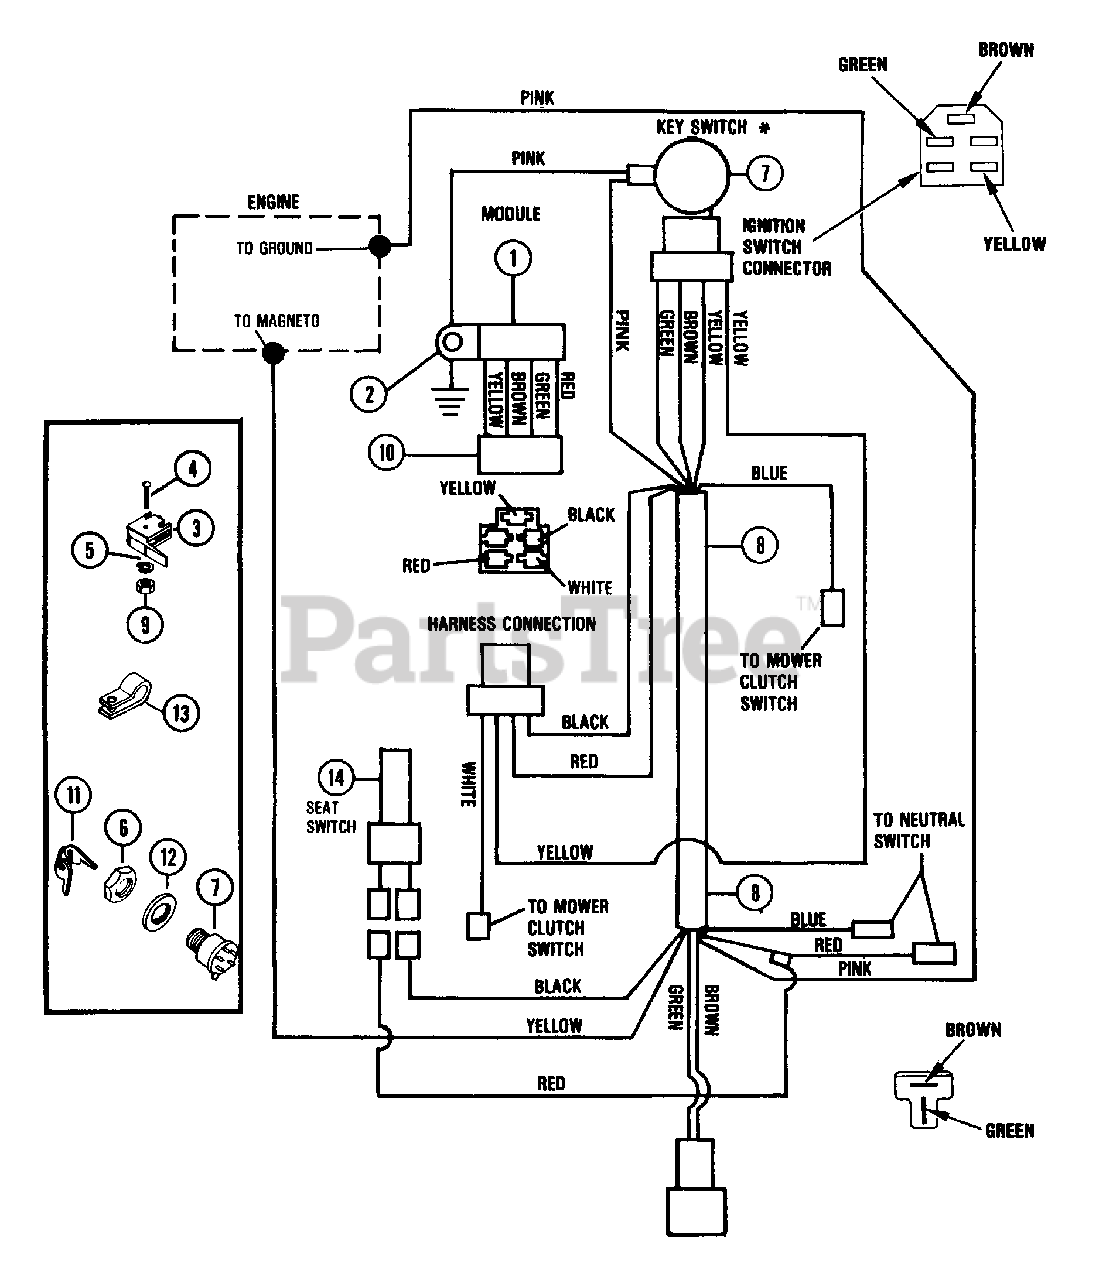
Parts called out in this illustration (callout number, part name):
1	MODULE
2	SCR-TAP 10-12X.50 CRPH PL A
3	SWITCH INTERLOCK
4	SCR-MCH 10-24X1.00 SLRH PL
5	WSHR-LK 10X.047 MED PL
6	NUT .625-32 ALUM
7	SWITCH & KEY SET ASSEMBLY
8	WIRE HARNESS
9	NUT-HEX 10-24 PL
10	CONNECTOR
11	KEYS
12	WSHR-LK-INT .625X.045 PL
14	SWITCH SEAT
